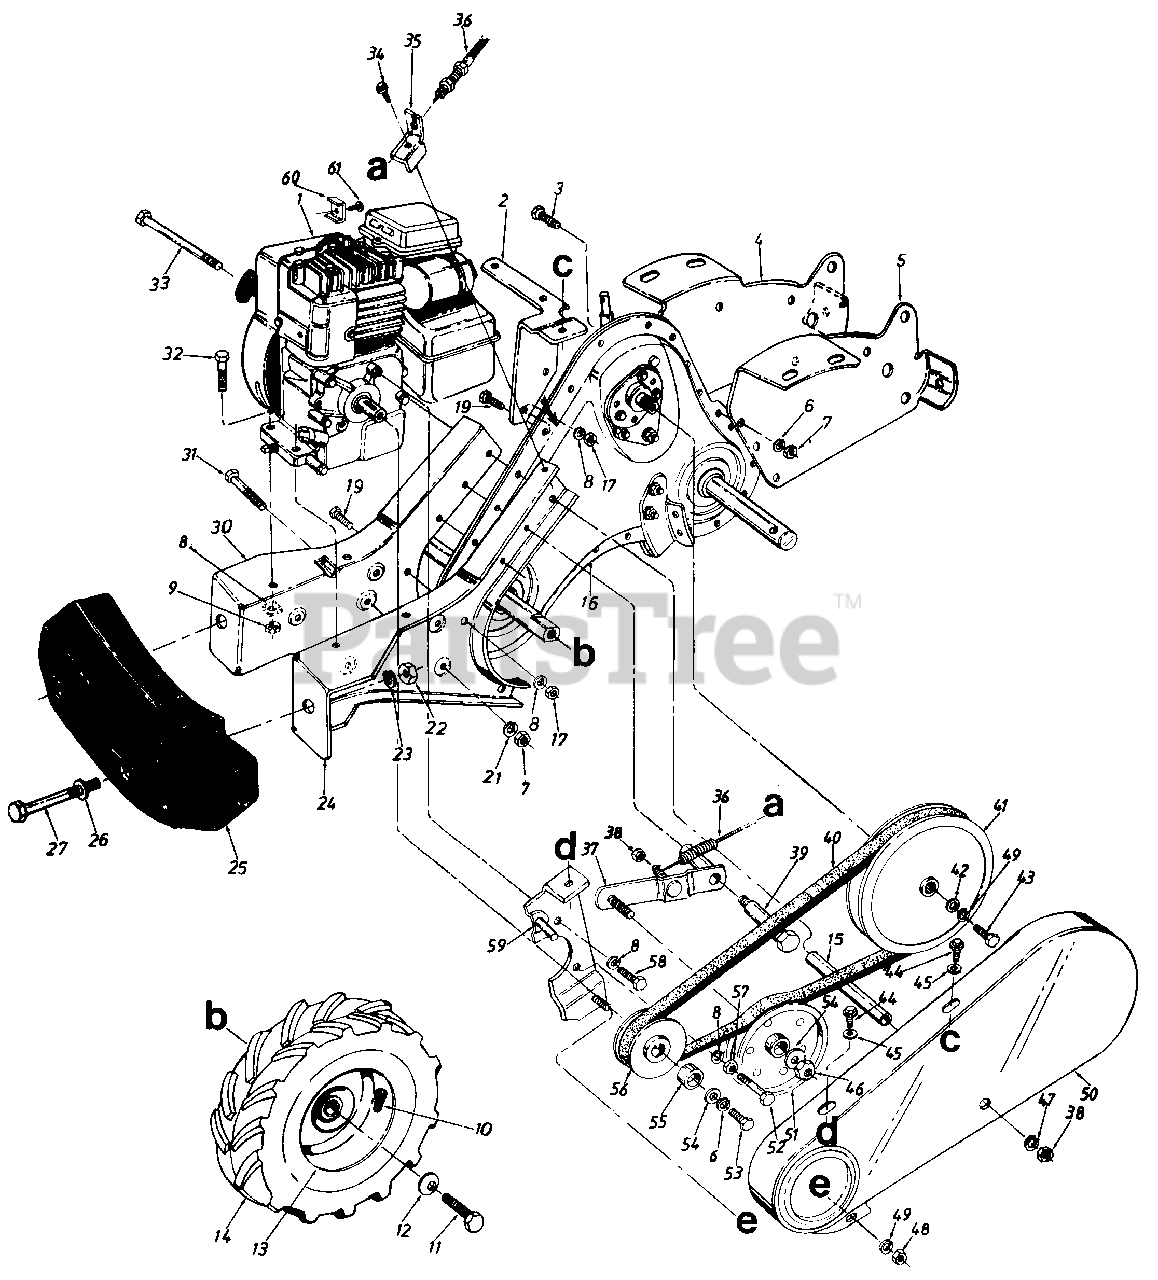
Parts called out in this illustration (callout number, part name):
1	Engine
4	Tine Shield Mtg. Brkt.-R.H.
7	Hex Nut 3/8-16 Thd.
8	L-Wash. 5/16" I.D.
9	Hex Nut 5/16-18" Thd.
10	Air Valve
11	Hex Bolt 5/16-24 x .62" Lg.
12	Bell-Wash. .345" I.D. x .88"
13	Wheel Rim Ass'y. Only
14	L.H. Wheel Ass'y. Comp.
14	R.H. Wheel Ass'y. Comp.
14	Tire Only 13 x 5.0
15	Spacer 3/8" I.D. x 8.38" Lg.
16	Transmission Comp.
17	Hex Nut 5/16-18 Thd.
19	Hex Bolt 5/16-18 x .75" Lg.
21	L-Wash. 3/8" I.D.-H.D.
22	Hex Nut 1/2-13 Thd.
23	L-Wash. 1/2" I.D.
26	Fl-Wash. .510" l.D. x 1.0"
27	Hex Bolt 1/2-13 x 5.00" Lg.
32	Hex Bolt 5/16-18 x 1.50"
33	Hex Bolt 5/16-18 x 4.75" Lg.-Gr. 2
34	Hex Wash. TT-Tap Scr. 5/16-18 x .62" Lg.
35	Bracket Clutch Cable
36	Clutch Control Cable 53" Lg.
39	Shld. Bolt .500" Dia. x 2.27"
40	V-Belt
41	V-Pulley Split 518" I.D.
42	Fl-Wash. 1/4" I.D. x 93" O.D.
43	Hex Bolt 1/4-28 x .75" Lg.
44	Hex Wash. Hd. S-Tap Scr. 1/4-20 x .50" Lg.
45	Fl-Wash. .281' I.D. x .625"
46	Hex Cent. L-Nut 3/8-24 Thd.
47	Fl-Wash. 5/16" l.D.
48	Hex Nut 1/4-20 Thd.'
49	L-Wash. 1/4" l.D.t
51	Fl-ldler w/Flanges 3.75" O.D.
52	Hex Bolt 5/16-24 x 1.75"
53	Hex Bolt 3/8-24 x 1.00" Lg.
54	Fl-Wash. 3/8" l.D. x 1.00"
55	Spacer .758" l.D. x .ggOn
56	Engine Pulley
57	Hex Nut 5/16-24 Thd.
58	Hex Bolt 5/16-24 x .62" Lp
61	Hex Sems Scr. #10-32 x .62n
